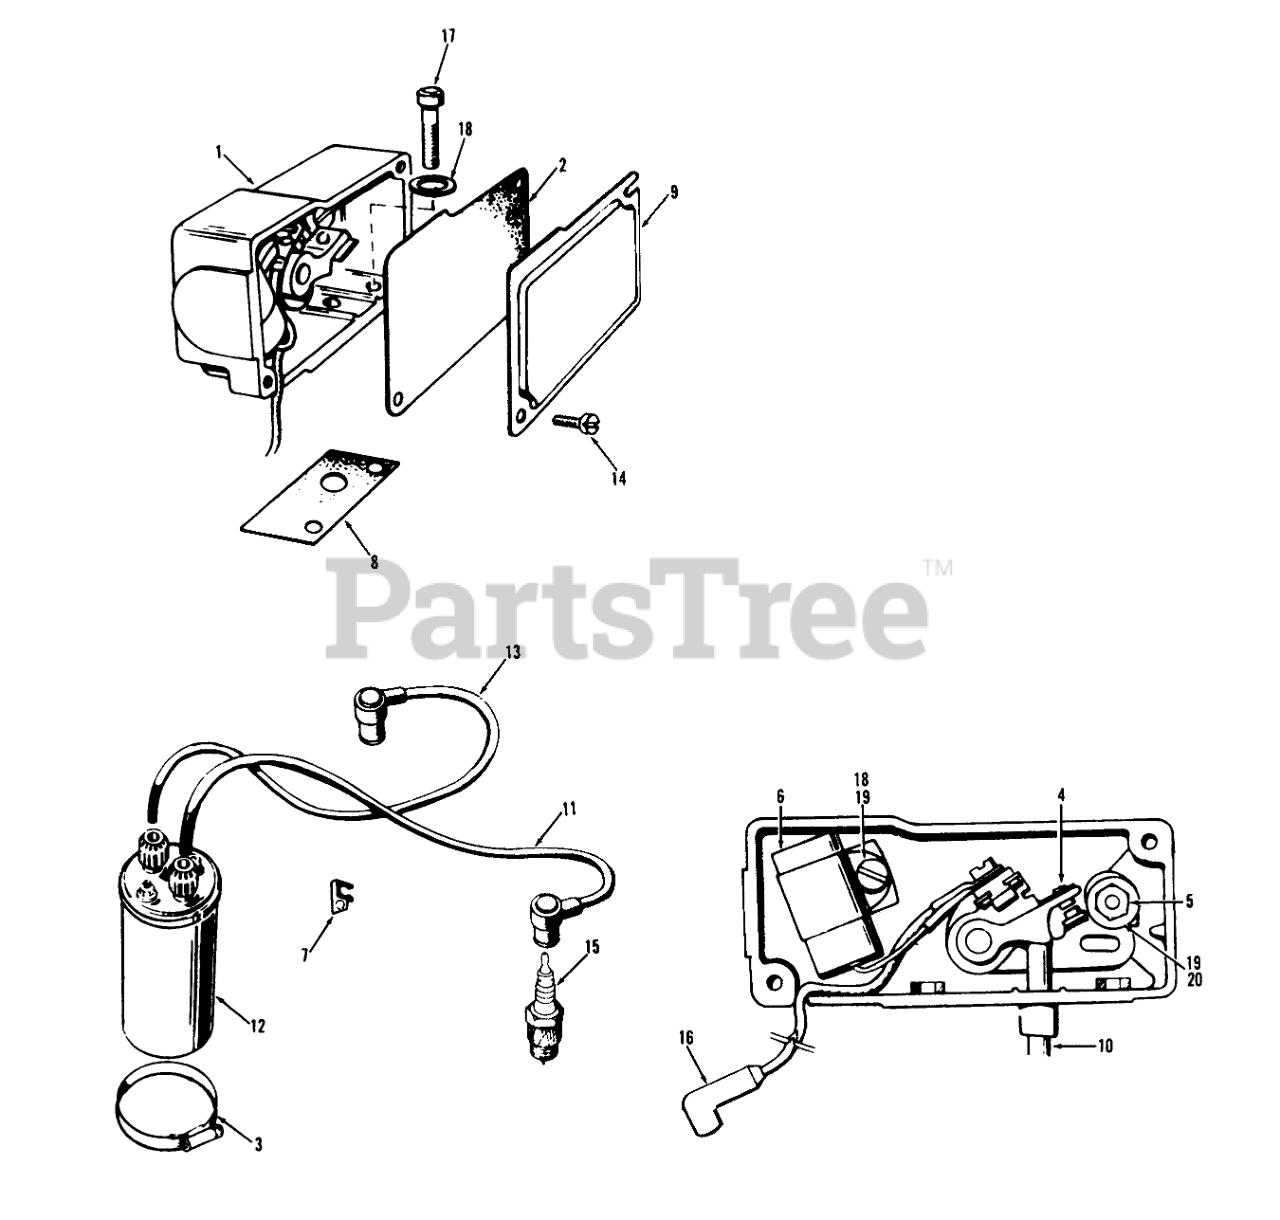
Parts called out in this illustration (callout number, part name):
1	Breaker Box
2	Gasket-Breaker Box Cover
3	Coil Mounting Clamp
4	SET-BREAKER POINT
6	CONDENSER-BRKER PTS
7	Clip,Spark Plug Cable
8	Gasket,Breaker Box Mounting
9	Breaker Box Cover
10	Plunger
11	Cable, Spark Plug (19")
12	Ignition Coil
13	Spark Plug Cable 16 3/4 in
14	Pan HD Screw 8-32 X 5/16
15	Spark Plug
16	Wire Assy-Points To Coil
17	Hex Bolt 1/4-20 X 3/4 in
18	Condenser Mounting (#8)
18	Breaker Box Mounting (1/4")
19	Pan HD Screw-Breaker Points
19	Pan HD Screw-Condenser
20	Nut-Breaker Points
